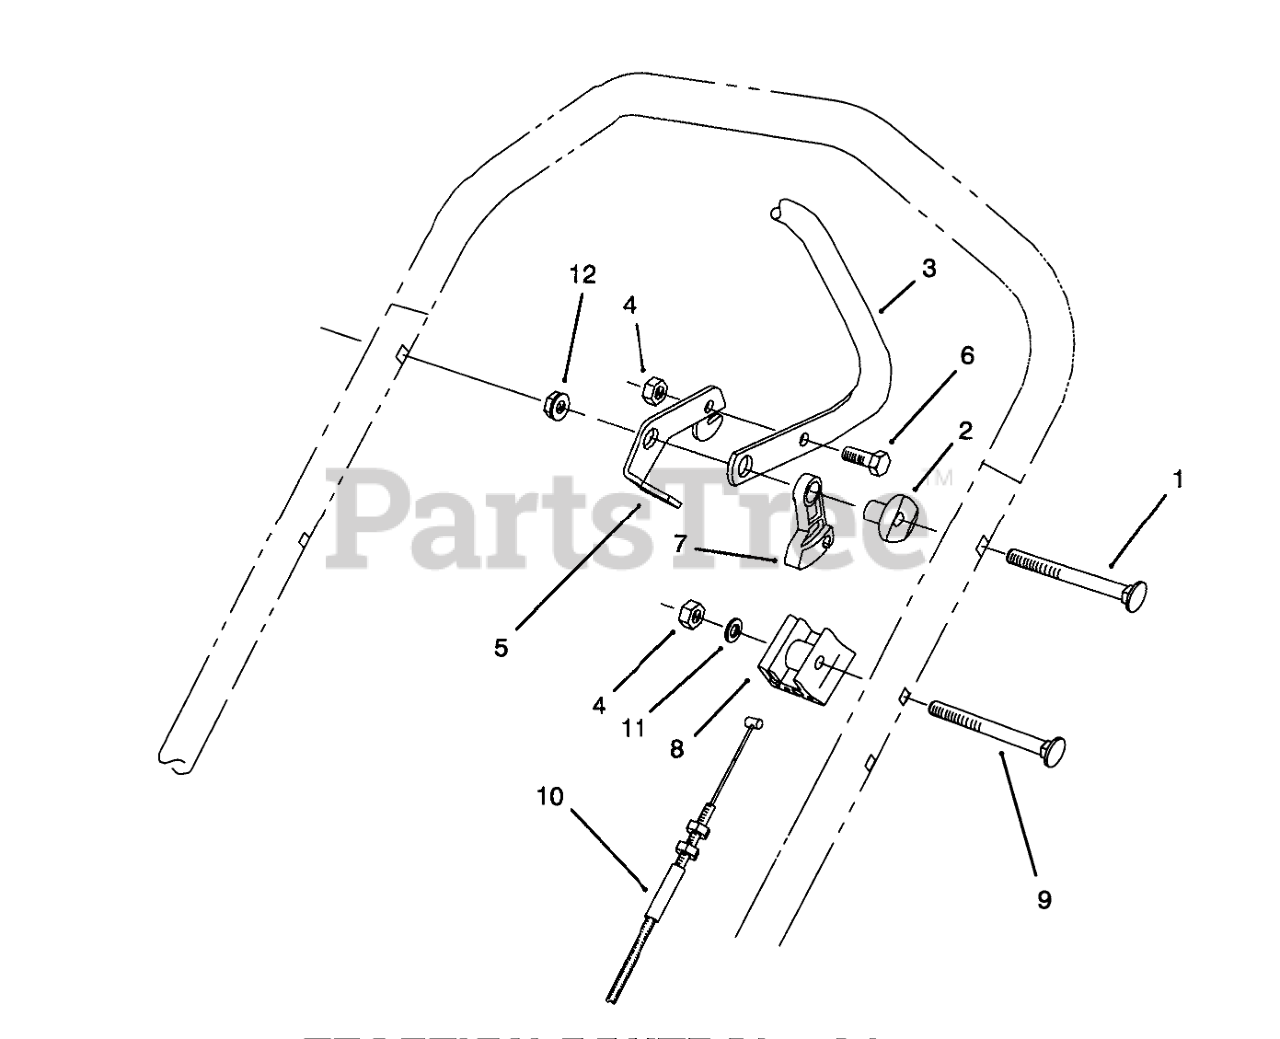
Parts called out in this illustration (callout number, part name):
1	SCREW-HANDLE
2	SPACER-SUPPORT
3	Bar-Control
4	NUT-LOCK, NI
5	LEVER-CONTROL
6	SCREW-HH
7	LEVER-TRACTION
8	SUPPORT-CABLE
9	SCREW-HANDLE
10	TRACTION CABLE
11	WASHER-FLAT
12	NUT-LOCK, NI
